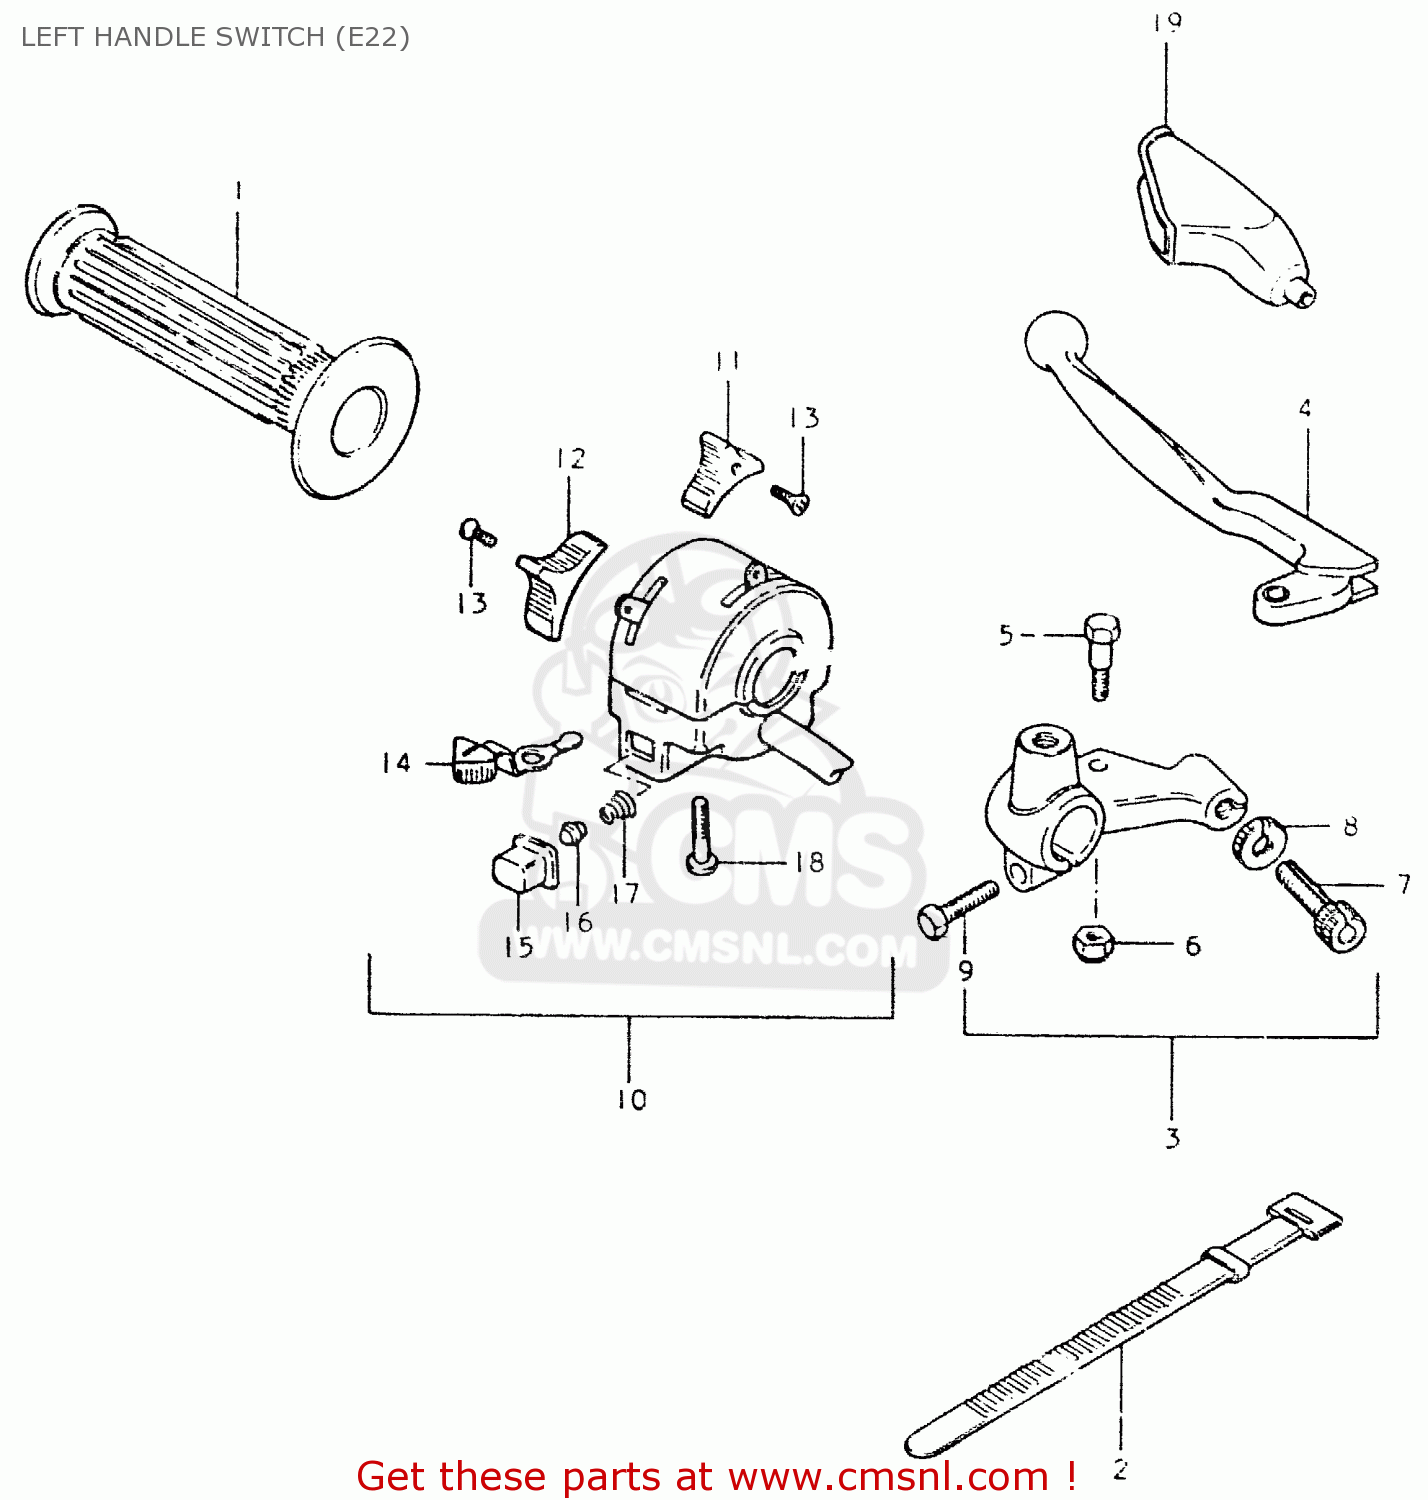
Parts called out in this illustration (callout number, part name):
1	GRIP,L
2	CLAMP(L:120)
3	LEVER ASSY,CLUTCH
4	LEVER,CLUTCH
5	BOLT,LEVER
6	NUT 6MM
7	ADJUSTER,CABLE
8	NUT,CABLE ADJUSTER
9	BOLT
10	SWITCH ASSY, HANDLE LH
11	KNOB,LIGHTING SWITCH
12	KNOB, DIMMER
13	SCREW
14	KNOB,TURNSIGNAL
15	BUTTON,HORN
16	CONTACT
17	SPRING
18	SCREW
19	COVER,CLUTCH LEVER
